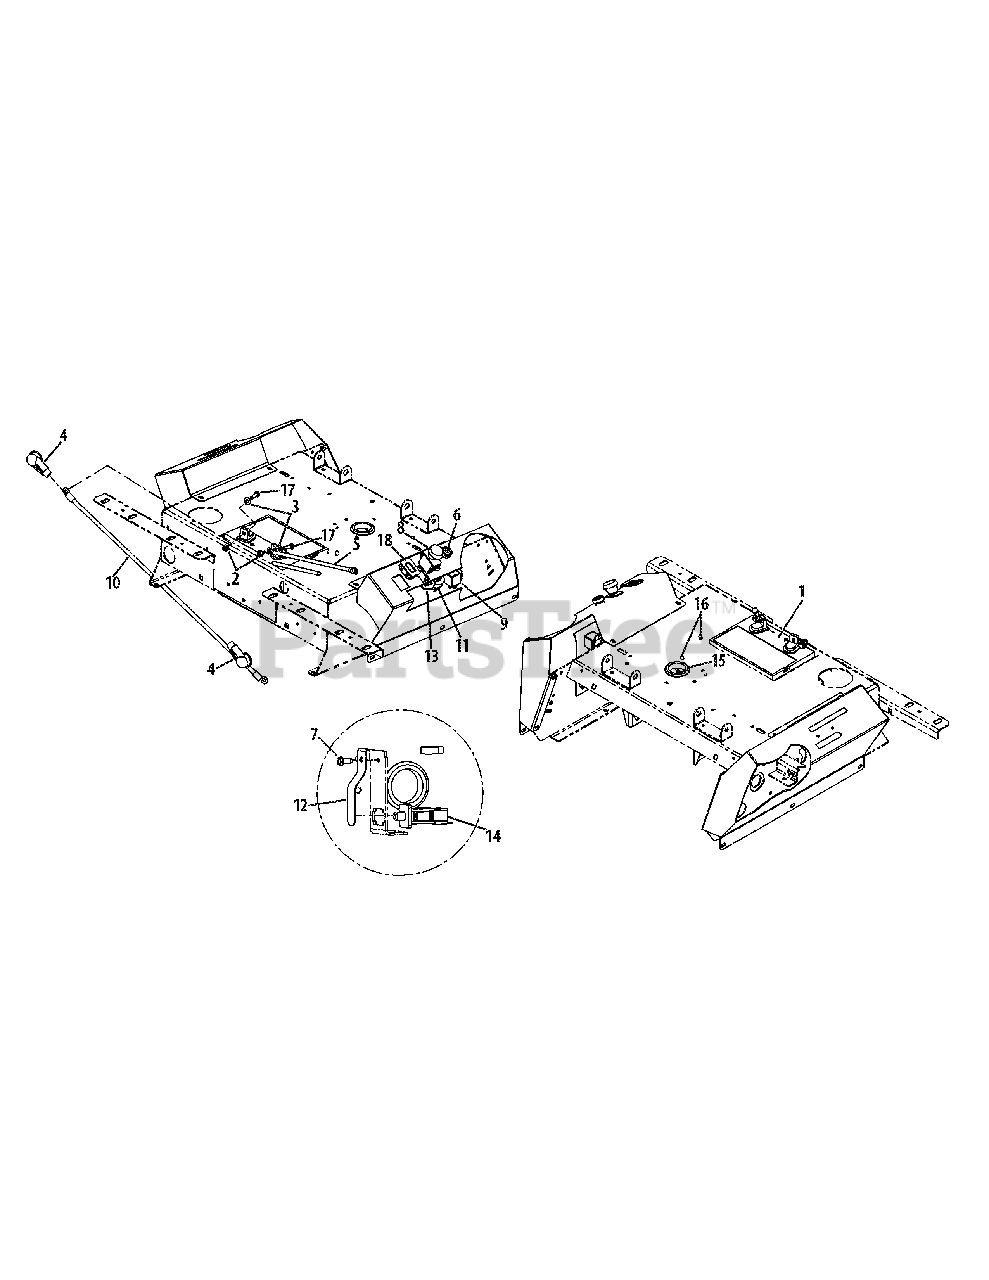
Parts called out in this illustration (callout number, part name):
2	Nylock Nut, 1/4-20
3	Washer, .281 x .625 x .063
4	Terminal Boot, 1.00 x 2.50
5	Battery Cable
6	Nut, 5/8-32
7	Flange Screw, #10-24 x .500
8	PTO Switch
9	12 V Relay
10	Battery Cable
11	Ignition Switch
12	Renovator Spring
13	PTO Bracket
14	Switch
15	Grommet, 1/8 x 1.5 x 2.13
16	Electrical Conduit Clip
17	Hex Screw, 1/4-20 x .75
